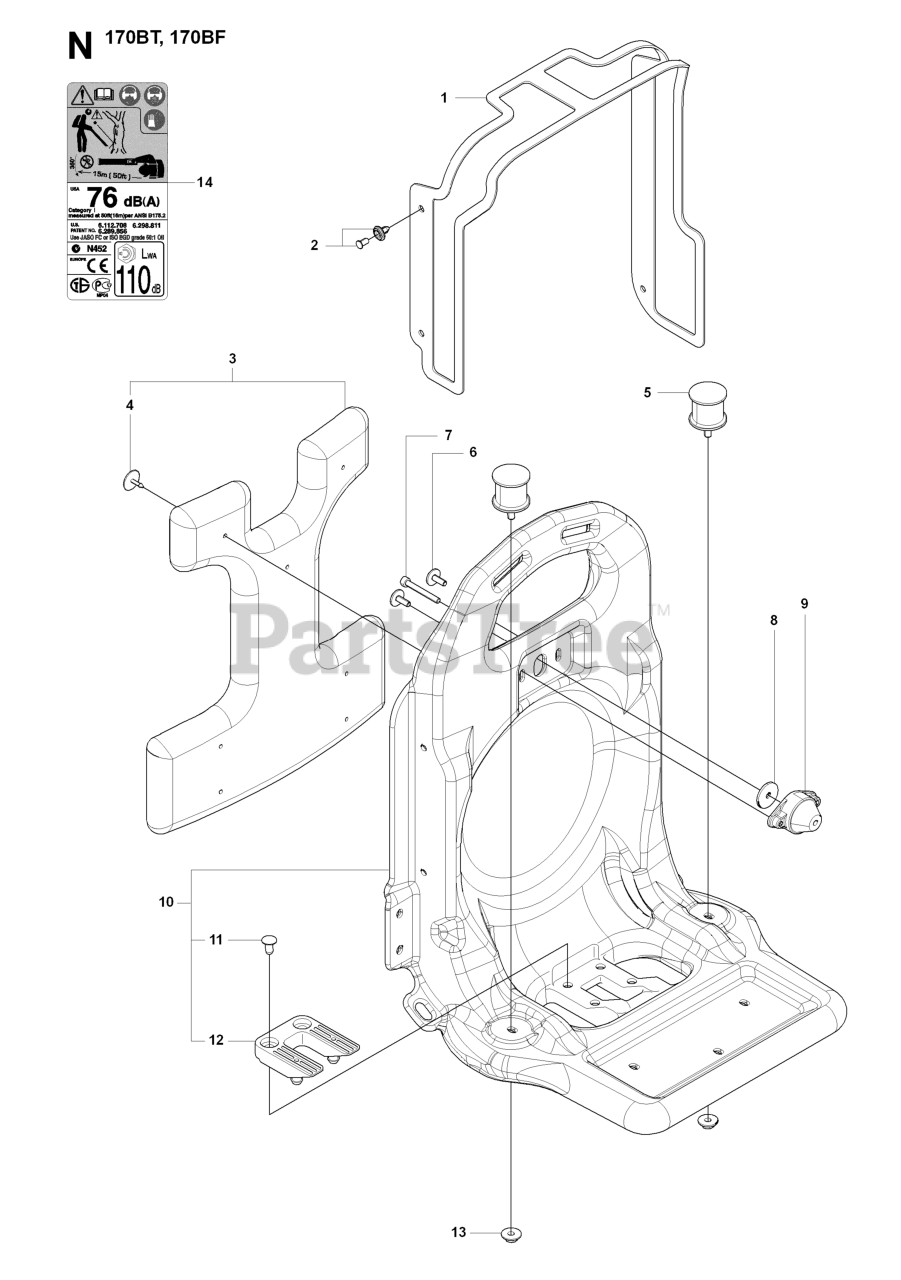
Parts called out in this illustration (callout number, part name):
2	CLIP
3	PAD COMP
4	CLIP
8	WASHER
9	DAMPER UPPER
11	CLIP
